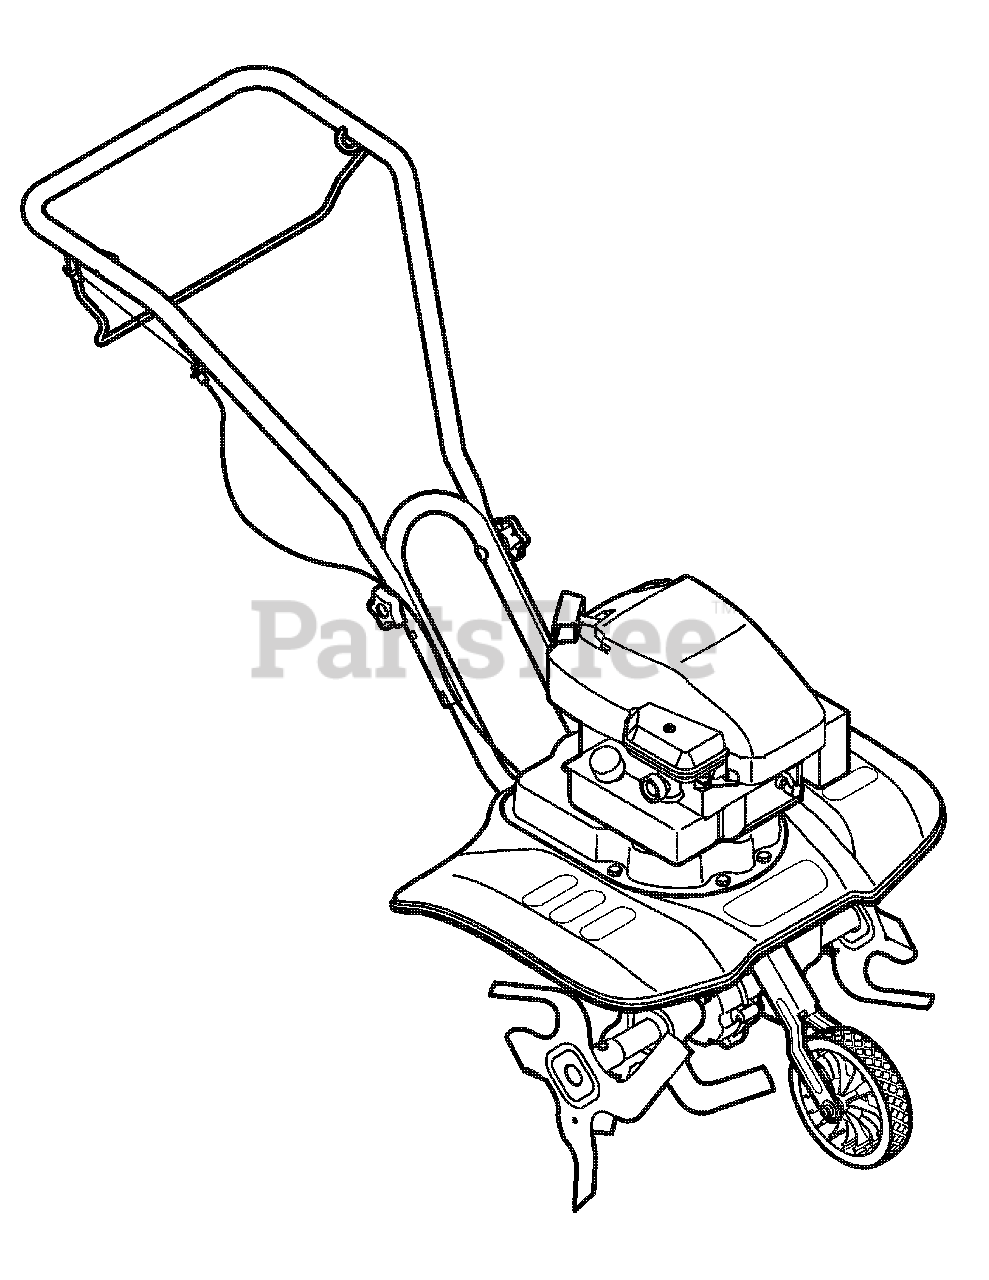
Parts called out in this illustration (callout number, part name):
NA	Pre Filter
NA	Drive Belt
NA	Clutch Cable
NA	Rim
NA	Tire
NA	Foam Grip
NA	Handle Knob
